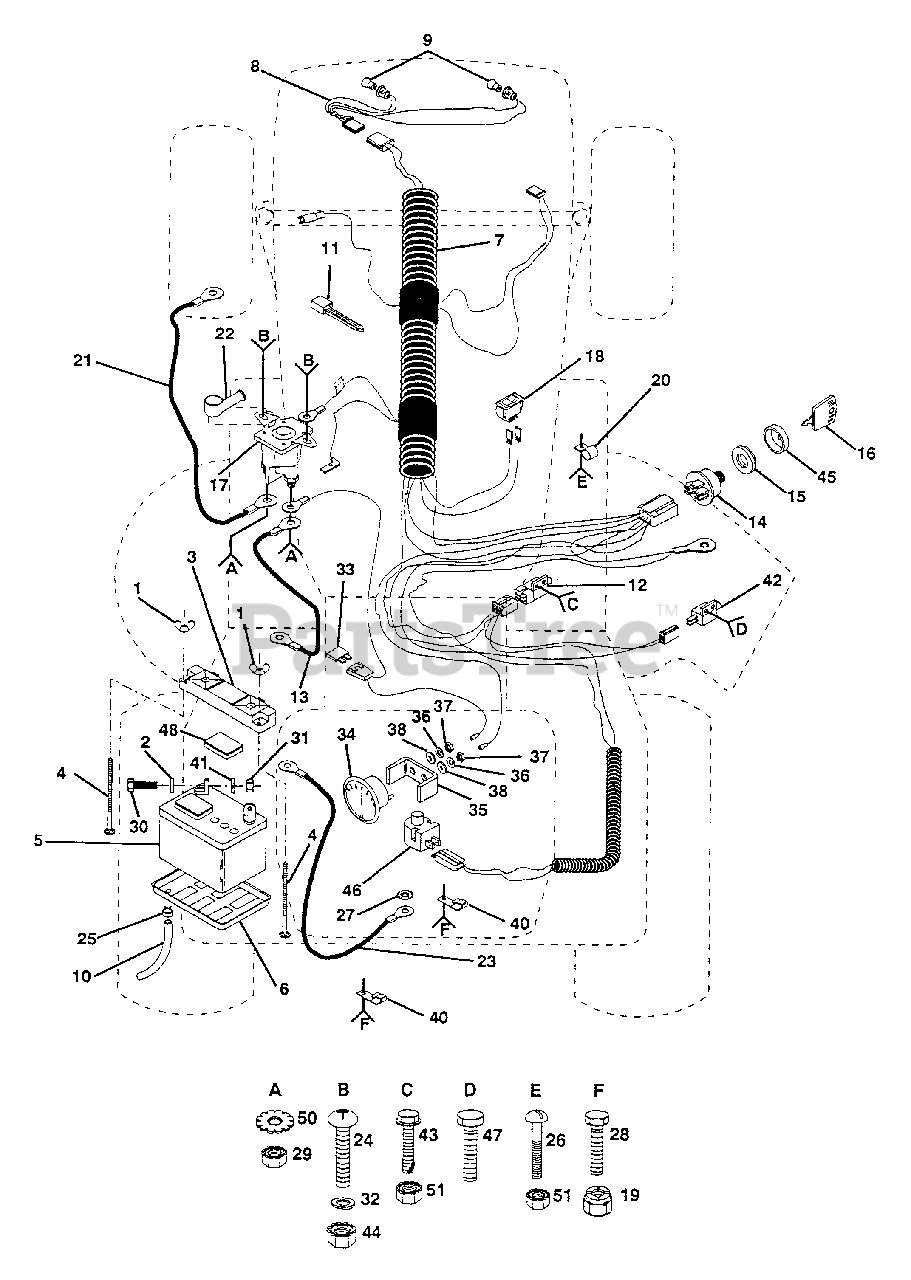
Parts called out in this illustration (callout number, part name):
1	Wing Nut 1/4 - 20
2	Washer 9/32 x 5/8 x 16 Ga.
3	Terminal Guard
4	Carriage Bolt 1/4 - 20 x 7-1/2
5	Battery
6	Battery Tray
7	Ignition Harness
8	Harness, Light Socket
9	Light Bulb
10	Tube, Battery Tray
11	Cable Tie
12	Switch, Interlock, Attachment Clutch
13	Cable, Battery
14	Switch, Ignition
15	Nut, Ignition
17	Solenoid
18	Switch, Light
19	Nut, Crownlock 1/4 - 20
21	Cable, Battery
22	Terminal Cover
23	Cable, Battery
24	Screw 10/32 x 1/2 Pan Head UNF
25	Clamp, Hose
26	Slotted Pan Head Screw #10-32
27	Washer, Lock Ext. Tooth
28	Bolt, Hex 1/4 - 20 x 1/2 Gr. 5
29	Nut, Keps, Hex 1/4- 20
30	Bolt, Hex 1/4 - 20 x 3/4
31	Nut, Hex 1/4 - 20
32	Washer, Lock 1/4 - 20 Ext. Tooth
35	Bracket, Ammeter
36	Washer, Lock Ext. 3/4
38	Washer, 7/32 x 1/2 x 18 Ga
40	Clip, Insulated
41	Lock Washer 1/4
42	Switch, Interlock, Clutch Pedal
43	Screw, Hex Washer Head
44	Nut, Keps #10-32 UNF
45	Cover, Switch Key
46	Switch, Plunger
47	Screw, Hex Tapping #10-24 x 1/2
48	Battery Caps Set
50	Washer, Lock 1/4
